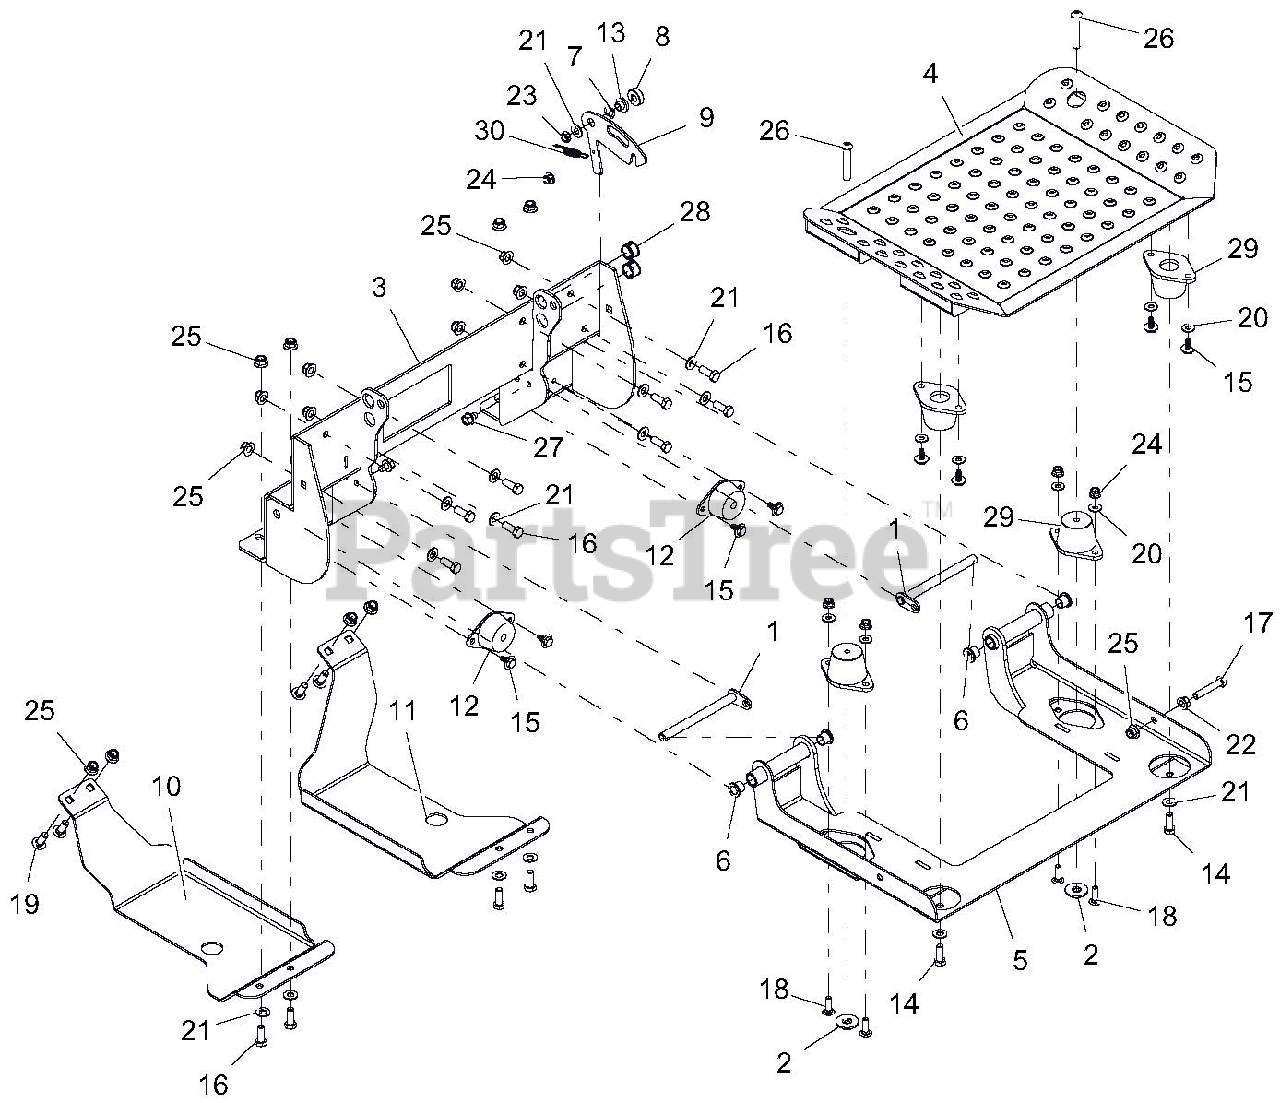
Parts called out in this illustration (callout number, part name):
1	WLDMT, PIN & LOCK
2	WLDMT, SEAT RETAINER
3	WLDMT, PLATFORM SUPPORT
4	WLDMT, PLATFORM TOP
5	WLDMT, PLATFORM CARRIER
6	BRG, FLG .500 X .620 X .500 BRNZ
7	WAVE WASHER .531X.781X.125 FH
8	SPCR, .375 X 1.00 X .342
9	LATCH, PLATFORM SIDE
10	PLATE, LH SKID
11	PLATE, RH SKID
12	MOUNT, ENGINE. VIBRATION ISO
13	BSHG, FLG .385 X .500 X .875 X .406
14	BLT-HEX .38-16X1.00 GR5 YWZC EP30
15	BOLT, 5/16-18X.625 SLF TAP FLG
16	BLT-HEX .38-16X1.00 GR5 YWZC
17	BLT-HEX .38-16X2.00 GR5 YWZC
18	BLT-RDHDSQSHNK .31-18X1.00 G5 Y
19	BLT-RDHDSQNK .38-16X1.00 G5 YWZC
20	WSHR-FL-STL.312X.734X.065 YWZ
21	WSHR-FL-STL.406X.812X.065 YWZ
22	@NUT-SPNLK-FLG .375-16 YWZC
23	@NUT-LK-CTR-JAM .375-16 YWZC
24	NUT-LK-NYL-FLG .31-18 YWZC
25	NUT-LK-NYL-FLG .38-16 YWZC
26	SCR-BTHD-SOCKET .38-16X2.25 FTH YWZC
27	SCR-TAP .38-16X.50 HWH TR YWZ
28	BUSH, PANEL SNAP .687X.875X.56
29	MOUNT, ISOLATOR
30	SPRG, EXTENSION
